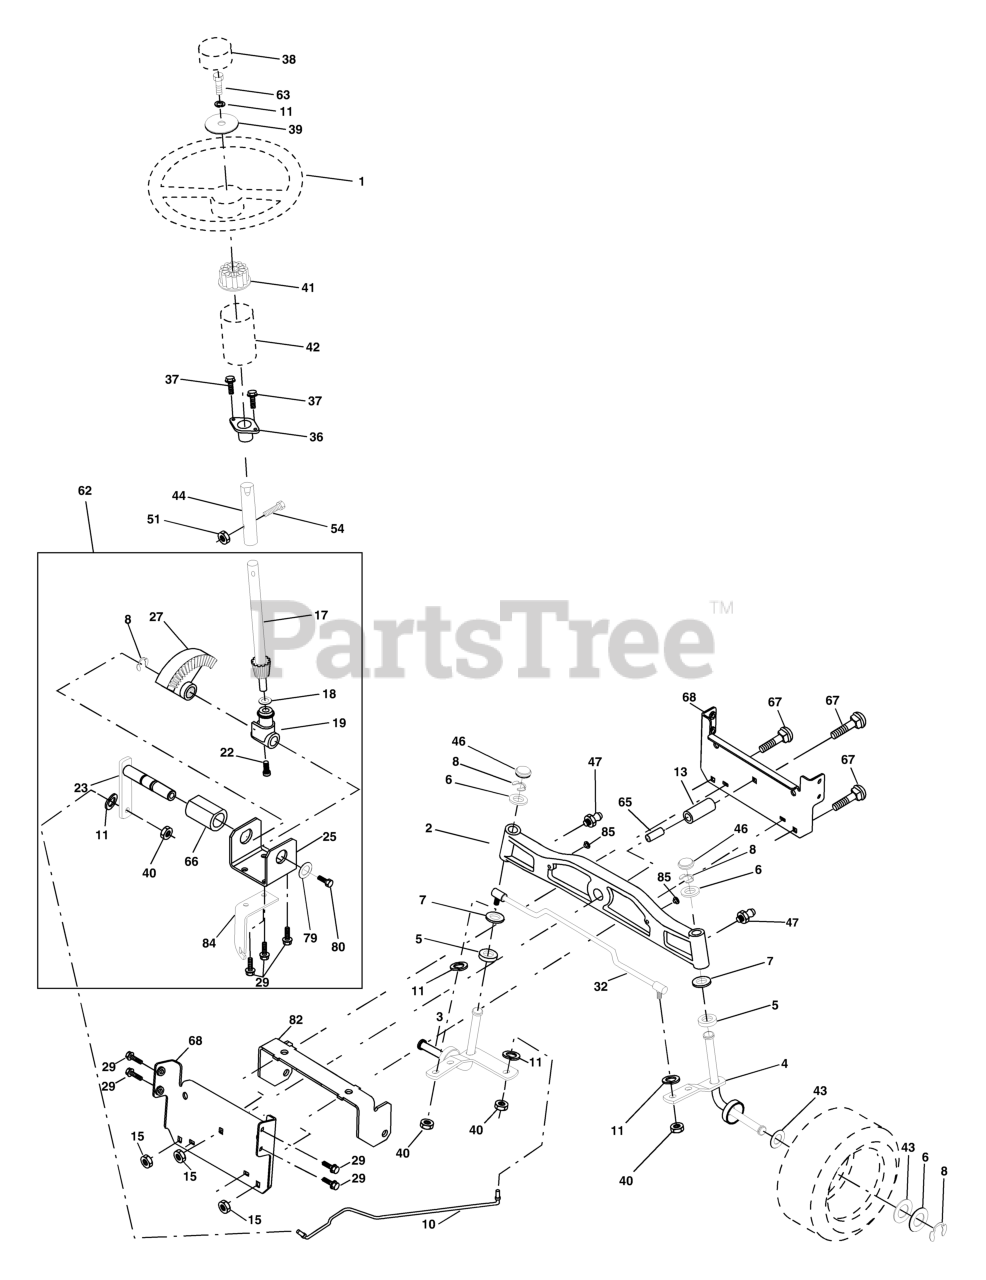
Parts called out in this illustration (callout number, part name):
1	STEERING WHEEL
2	AXLE
3	SPINDLE.ASM.LH.15"TIRES
4	SPINDLE.ASM.RH.15"TIRES
5	THRUST WASHER
10	DRAGLINK.15".TIRES
11	WASHER, LOCK 3/8
13	TUBE, PIVOT AXLE
15	NUT
17	SHAFT ASM STEERING
18	THRUST WASHER
19	STEERING SHAFT SUPPORT
22	SCREW.HX.WSH.HD
23	SHAFT ASSY PITTMAN
25	BRACKET STEERING
27	GEAR.SECTOR
29	SCREW 3/8-16X3/4
32	ROD.ASM.TIE.BALL.JOINT.NOVAN
36	BUSHING, STEERING
37	SCREW.TT.#10-32X.5.3/8.FLANGE
38	CAP.WHEEL.STEERING.GREY
39	Washer 13/32 x 1-1/20 x 11 Gauge
40	GRIPCO NUT
41	STEERING WHEEL ADAPTOR
42	BOOT STEERING
44	EXT SHAFT STEERING
46	CAP.SPINDLE.BLACK
47	ZERK M
51	NUT.71038.31-18.HEX.NYLOCK
54	BOLT.5/16-18X1-1/4 FULL.THREAD
62	STEERING KIT
63	BOLT
65	SPACER BRACE AXLE
66	BEARING ARM
67	BOLT CARRIAGE
68	AXLE, BRACE
79	WASHER
80	BOLT.HX.NYLON3/8-16X
82	BRACKET
84	Bracket Cable Clutch Chassis
85	FASTENER.XMAS.TREE
